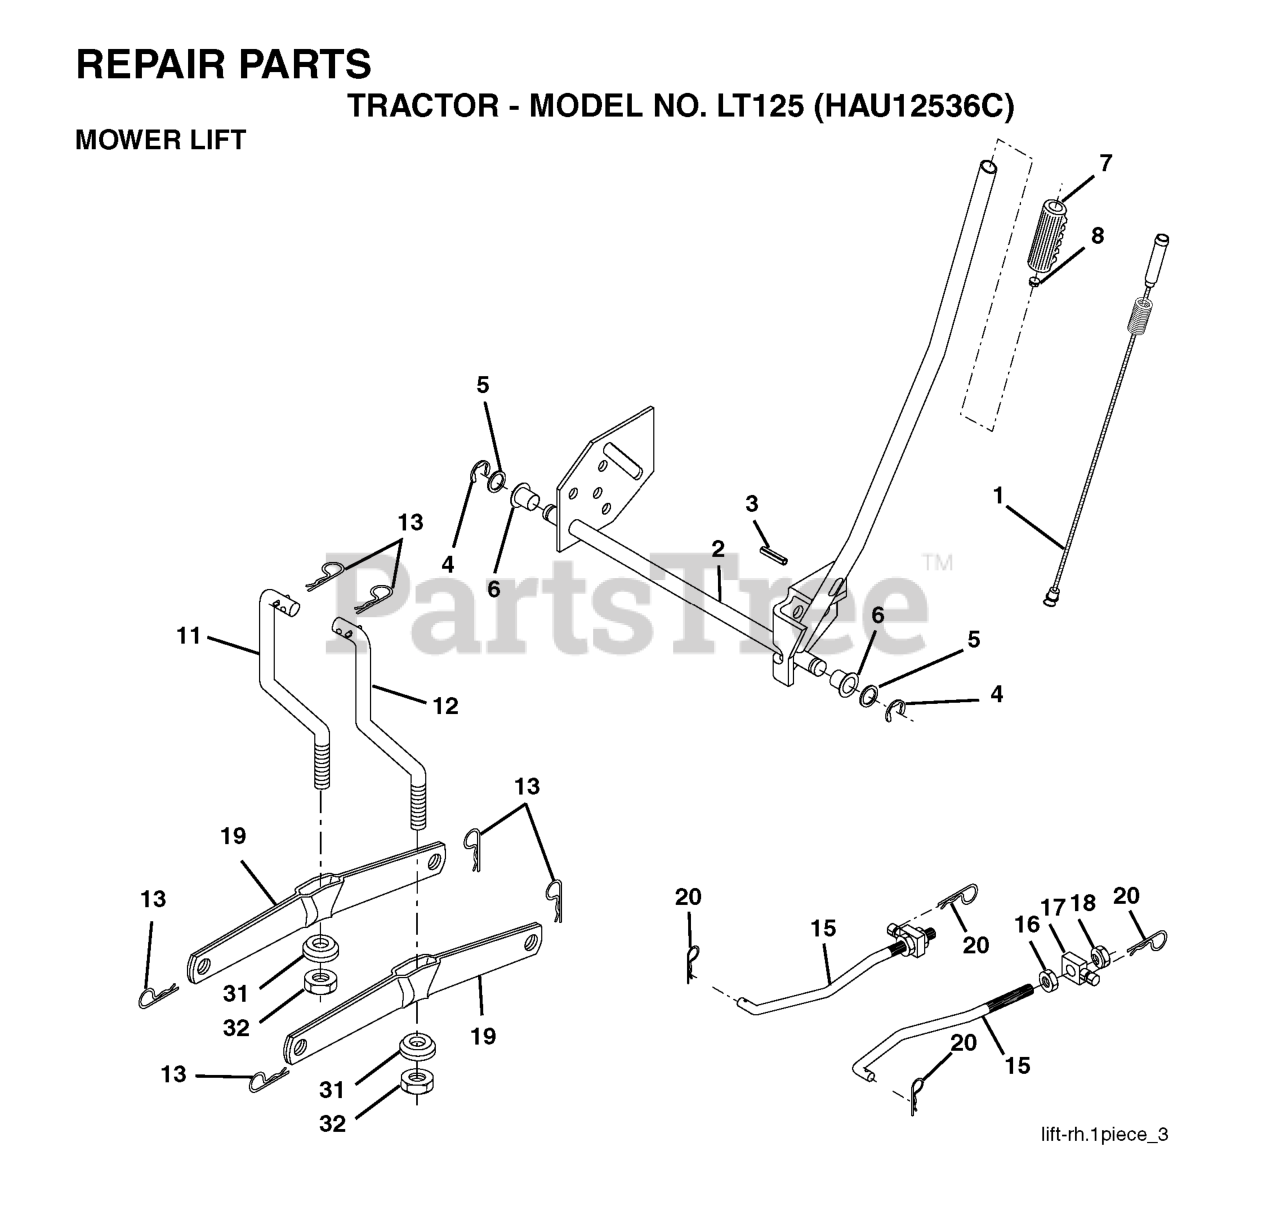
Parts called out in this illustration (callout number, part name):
1	WIRE ASM INNER W/ PLUNGER LT
2	SHAFT ASM R HANDLE
3	PIN GROOVE.
4	RETAINING RING LT
6	BEARING.NYLON
8	PLUNGER BUT KIT
11	LINK LIFT LH
12	LINK LIFT RH
13	RETAINER-SPRNG RB
15	LINK.SUSPENSION.FRONT
16	NUT.HEX.JAM.1/2-13
18	NUT.LK.W/WSH.1/2.
19	ARM.REAR.SUSPENSION
20	SPRING RETAINER
31	BEARING.PIVOT.LIFT
32	NUT CROWNLOCK 3/8-24
